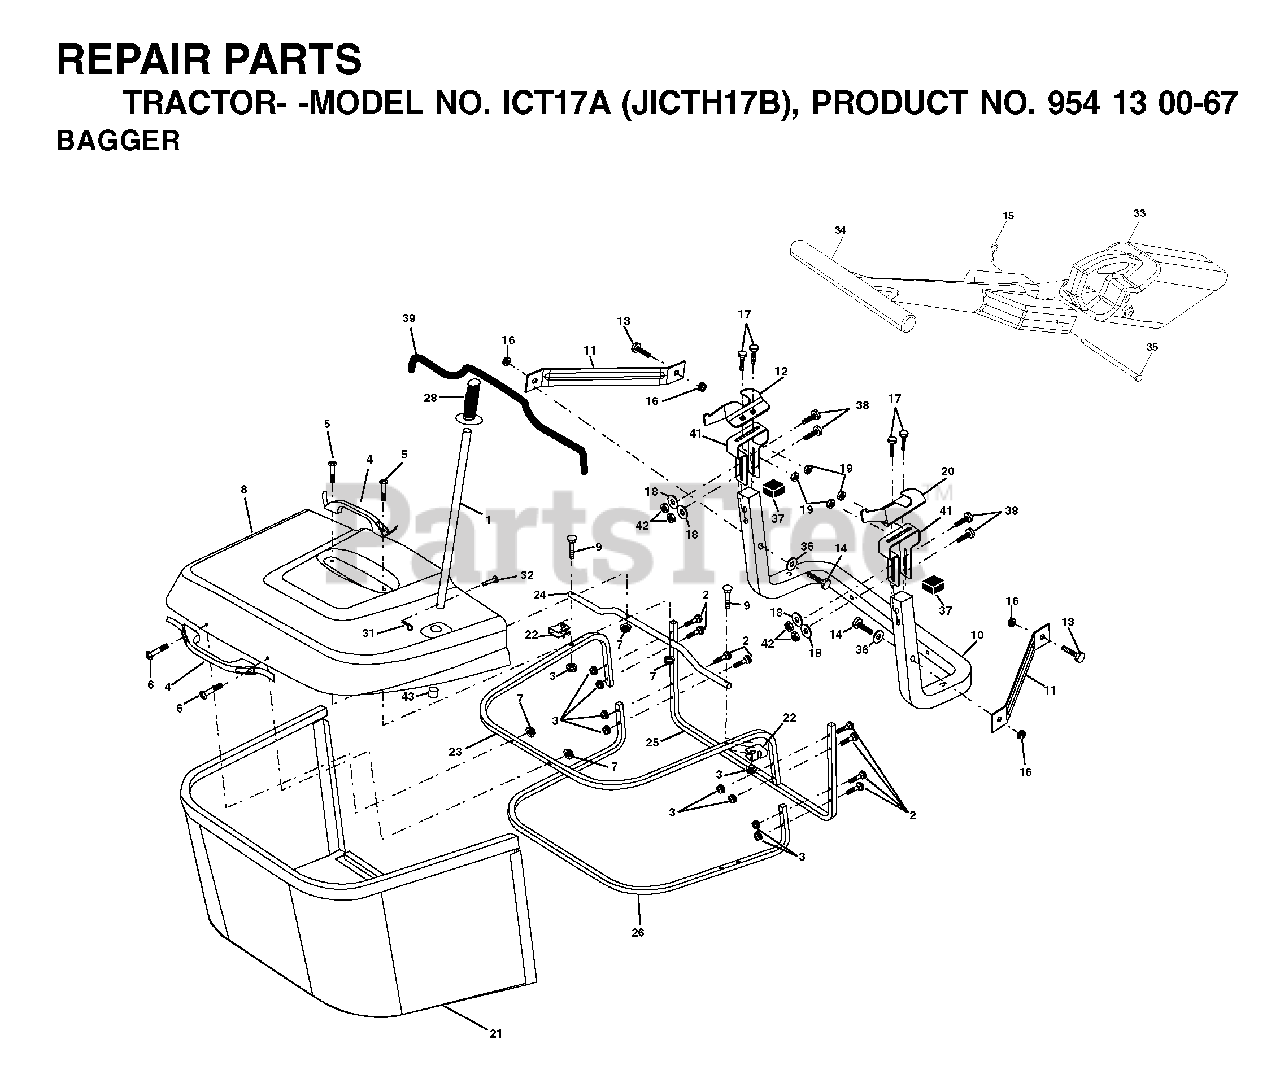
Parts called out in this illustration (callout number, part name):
1	TUBE HANDLE
3	NUT T
5	SCREW.PAN.HEAD
11	BRACKET
14	BOLT-HEX EAK
15	RETAINER-SPRNG RB
16	NUT LOCK FLG 3/8-16 UNC
17	BOLT
18	WASHER M
19	NUT LOCK HEX FLANGE 5/16-18
20	BRACKET
21	GRASS BAG
22	BRACKET
23	TUBE
24	TUBE
26	TUBE
28	GRIP.HANDLE.BLACK
31	RETAINER M
32	RIVET,DRILLED
33	MULCH PLUG, CTH150
35	PIN
36	WASHER
38	BOLT.5/16-18X2.5
41	BRKT, BAGGER
42	NUT.71038.31-18.HEX.NYLOCK
43	PLUG, TUBING END
